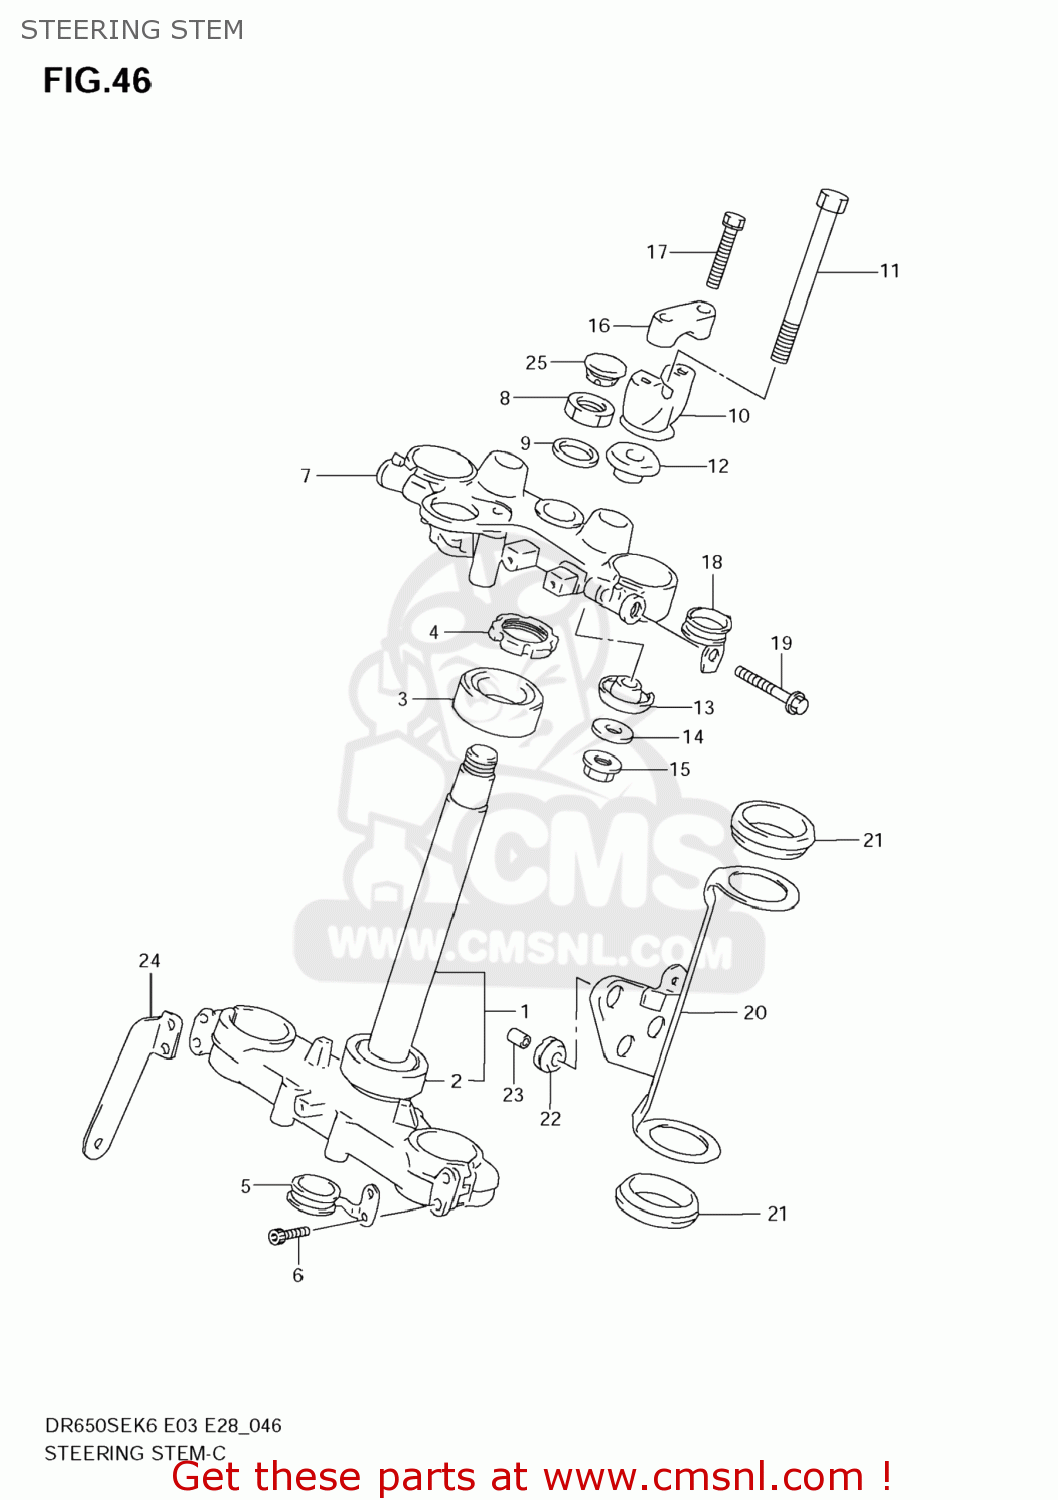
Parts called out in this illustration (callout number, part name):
1	STEM,STEERING
2	BEARING(30X52X16)
3	BEARING(30X52X16)
4	NUT,STEERING
5	GUIDE,BRAKE HOSE LWR
6	BOLT
7	HEAD,STEERING STEM
8	NUT
9	WASHER,STEM HEAD(24.5X34X1.6)
10	HOLDER,HANDLE LWR
11	BOLT
12	DAMPER,UPR
13	DAMPER,LWR
14	WASHER(10.5X28X2.3)
15	NUT
16	HOLDER,HANDLE(BLACK)
17	BOLT
18	CLIP
19	BOLT
20	COVER,FORK,R
21	DAMPER,HEADLAMP HSG BRACKET
22	CUSHION
23	SPACER(6.5X10X10)
24	BRACKET,FR SIDE REFLECTOR,R
25	CAP(OD:20)
